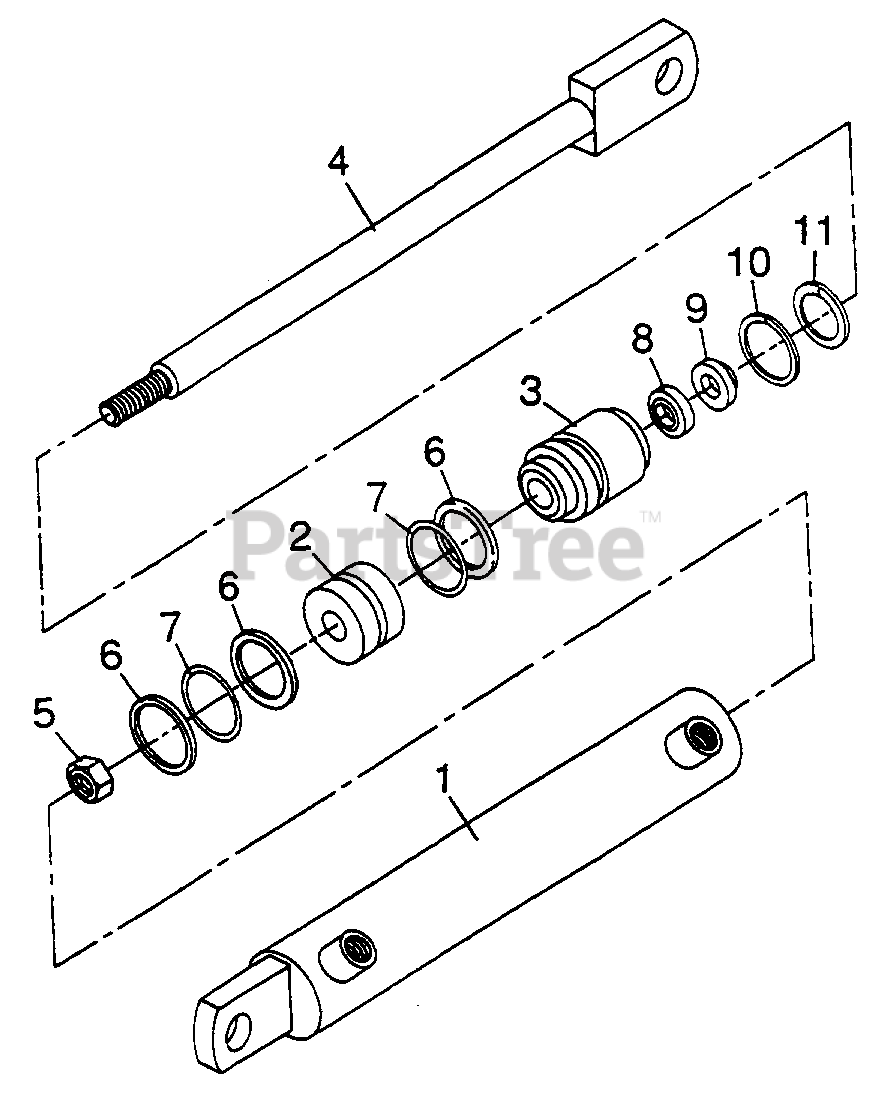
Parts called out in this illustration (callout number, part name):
1	Cylinder body 1.5 ID w/c
2	Piston, alum 1-1/2 O.D.
3	Guide 1-1/2 O.D.-3/4 I.D.
4	Rod .75 Dia w/c
5	1/2-20 Locknut
6	1.25 x 1.50 Backup ring
7	1-1/4 x 1-1/2 O-Ring
8	.25 x .75 x 1.00 U-cup lip
9	3/4 Wiper ring
10	1-1/2 Internal retaining ring
11	1-5/16 External retaining ring
